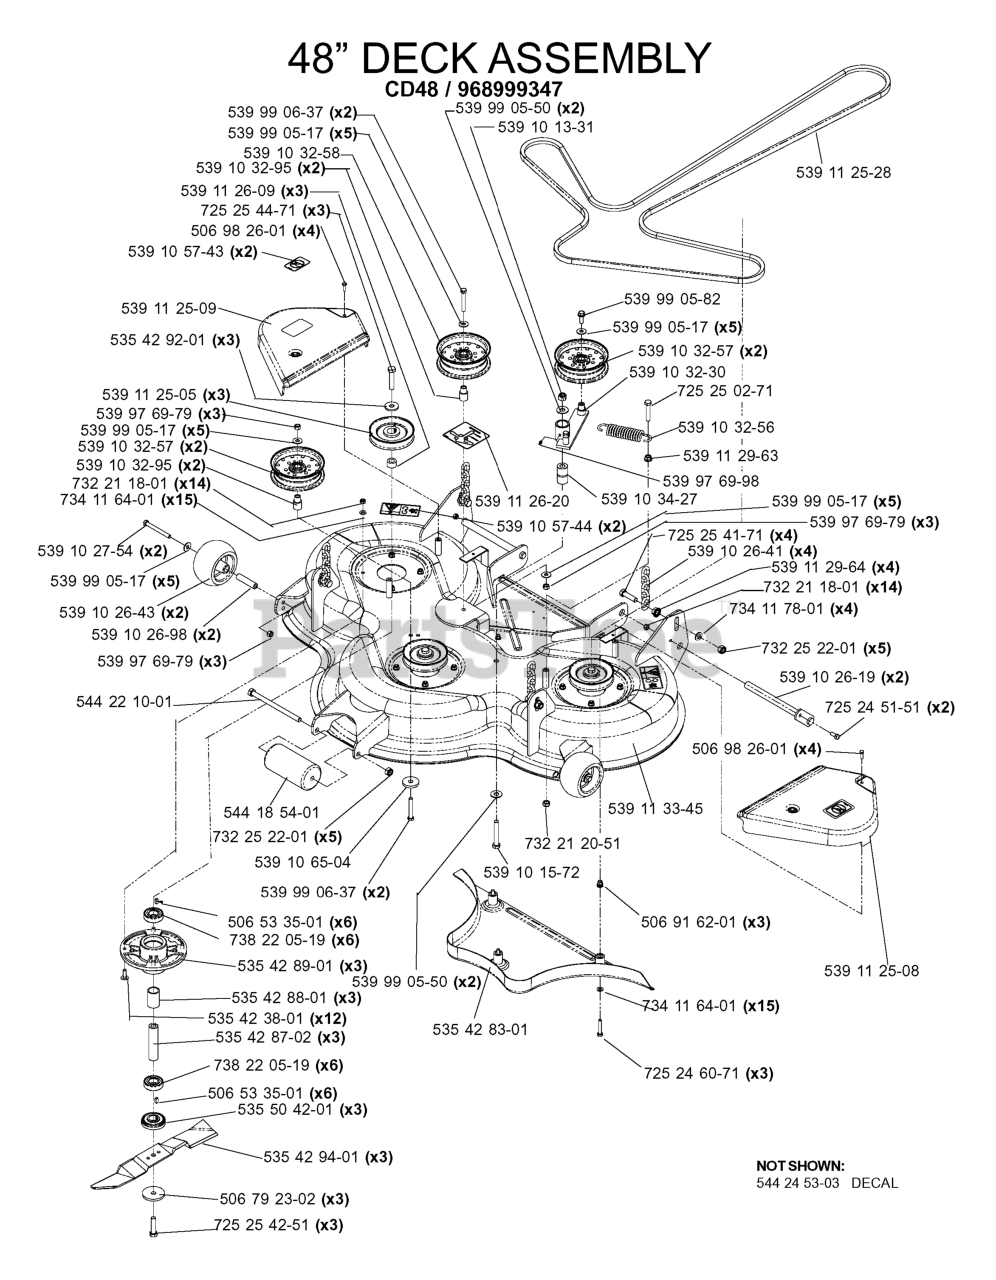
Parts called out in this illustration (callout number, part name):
1	SERVICE KIT TRIGGER ASSEMBLY
2	SERVICE KIT FUEL HOSE ASSEMBLY
3	RP FUEL FILTER
4	FUEL TANK BUSHING
5	FUEL TANK ASSY WELDED 38 CC LO
6	SERVICE KIT LATERAL SUPPORT
7	VALVE-CHECK (DUCKBILL)
8	VENT,FUEL TANK 36/41
9	ASSY TANK CAP GREY
